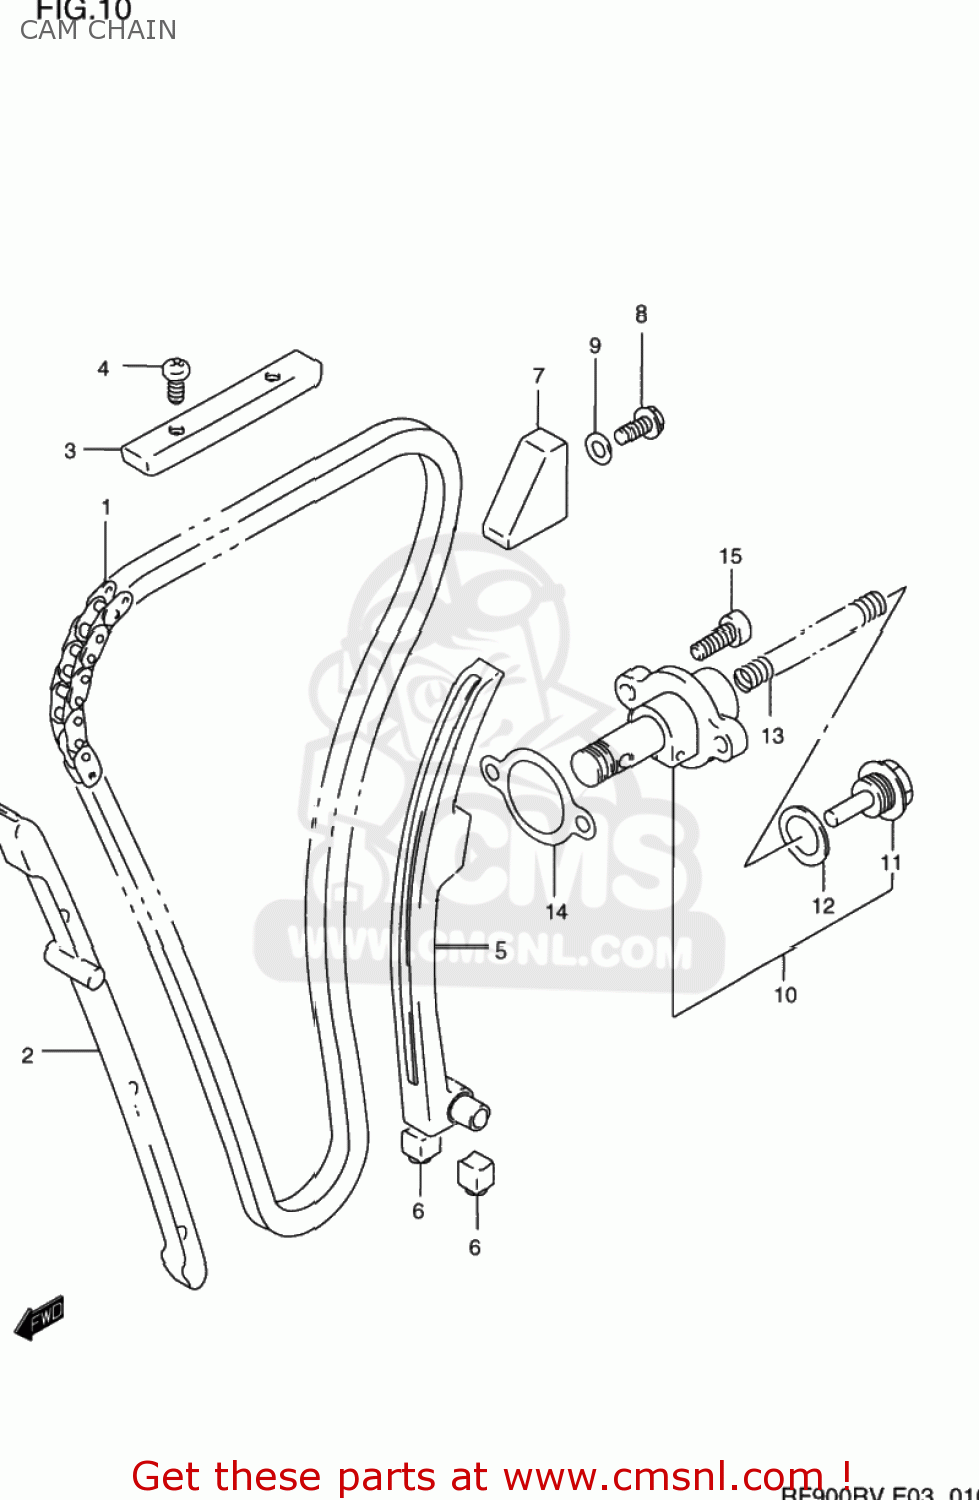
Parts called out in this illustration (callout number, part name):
1	CHAIN,CAMSHAFT DRIVE
2	GUIDE,CAM CAHIN NO.1
3	GUIDE,CAM CHAIN NO.2
4	SCREW
5	TENSIONER,CAM CHAIN
6	CUSHION,CAM CHAIN TENSIONER
7	GUIDE,CAM CHAIN NO.3
8	BOLT
9	GASKET(5.8X13X1.2) (NAS)
10	ADJUSTER ASSY,TENSIONER
11	PLUG
12	GASKET (NAS)
13	SPRING
14	GASKET,TENSIONER ADJUSTER (NAS)
15	BOLT
